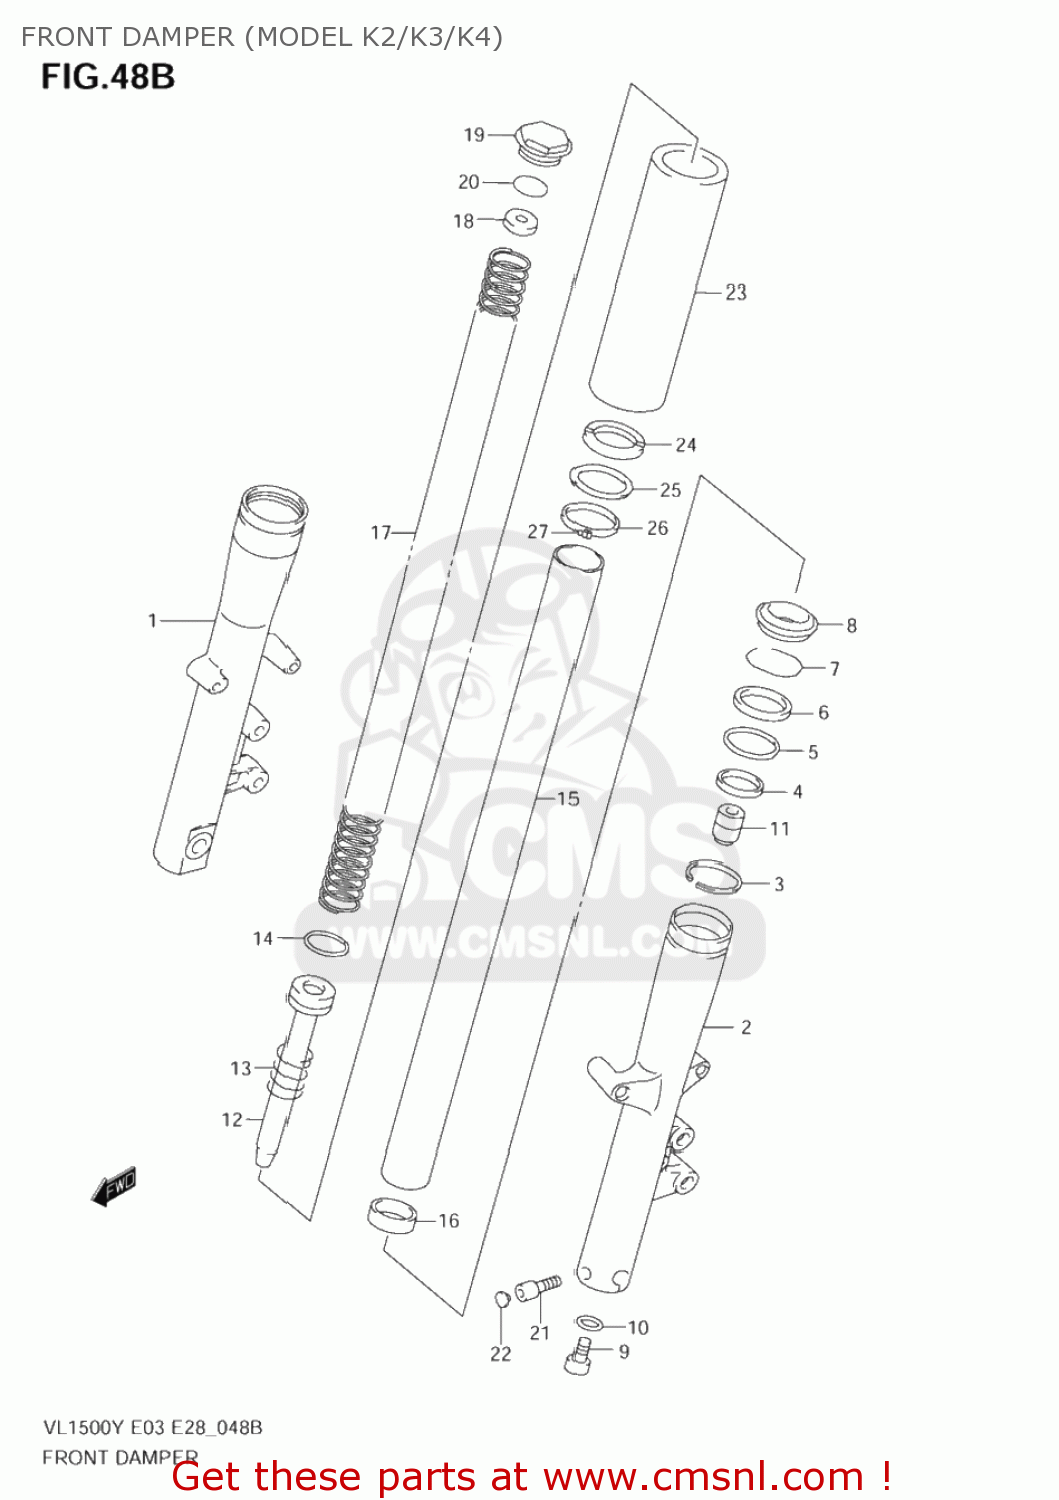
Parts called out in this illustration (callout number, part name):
1	TUBE,OUTER,R
2	TUBE,OUTER,L
3	GUIDE,CASE
4	BUSH,GUIDE
5	SPACER,SEAL
6	SEAL,OIL
7	CIRCLIP,FORK OIL SEAL
8	SEAL,DUST
9	BOLT,CENTER (8X18)
10	GASKET (NAS)
11	PIECE,OIL LOCK
12	SEAT,PIPE
13	SPRING,REBOUND
14	RING,PISTON
15	TUBE,INNER
16	BUSHING,SLIDE
17	SPRING,FR
18	BOLT,FORK INNER
19	BOLT
20	O RING
21	BOLT
22	CAP(OD:14.5)
23	CASE,UNDER
24	SEAT,RUBBER
25	WASHER
26	SPACER
27	BOLT
